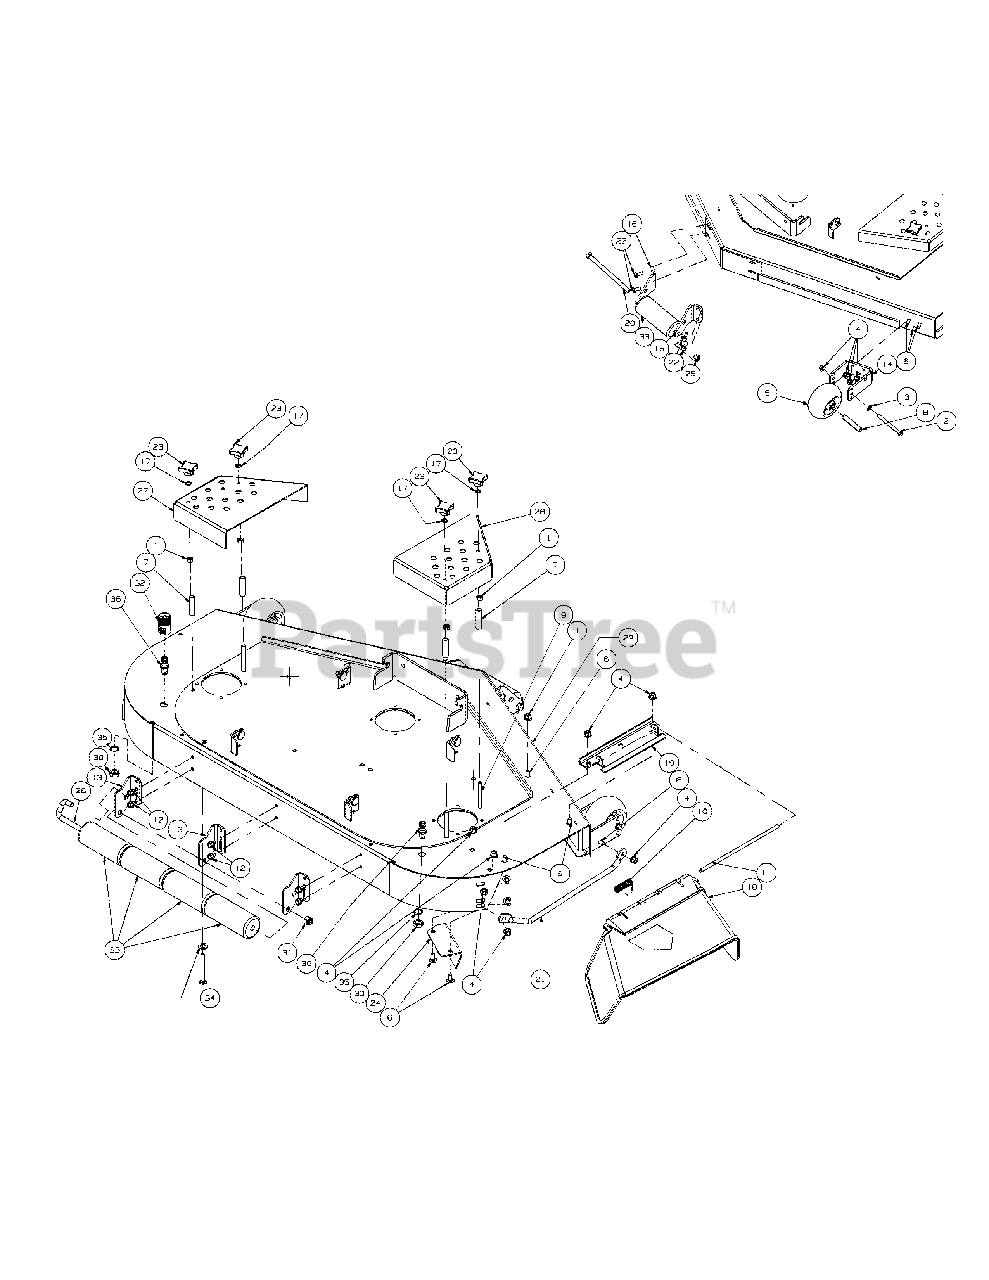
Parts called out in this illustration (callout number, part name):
1	Nut, 3/8-16, Hex
2	Hex Cap Screw, 3/8-16, 3.75
4	Hex Nut, 3/8-16 Flange Lock
5	Complete Wheel, 5.00 Dia
6	Carriage Bolt 3/8-16 x .75
8	Wheel Spacer
9	Carriage Bolt, 3/8-16 x 3.50
10	Torsion Spring
11	Chute Deflector Rod
12	Self Tapping Screw, 5/16-18 x 1/2
17	External Washer, 3/8
18	Deflector Chute
19	Deflector Chute Bracket
20	Hex Cap Screw, 1/2-20 x 7.50
21	Fabricated Deck Finger Guard
22	Self Tapping Screw, 3/8-16 x 0.875
23	Plastic Knob
24	Fabricated Deck, Chute Bracket
25	Lock Nut, Nylon Insert, 1/2-20
26	J-Hook w/ Threaded Roller
30	Hex Nut, M16-1.5
31	Hex Nut, 1/2-13, Insert Lock
32	Water Nozzle Adaptor
33	Front Roller
34	Washer, .510 x 1.00 x .060
35	Lock Washer, 17 x 23.8 x 1.95
36	Deck Water Nozzle
